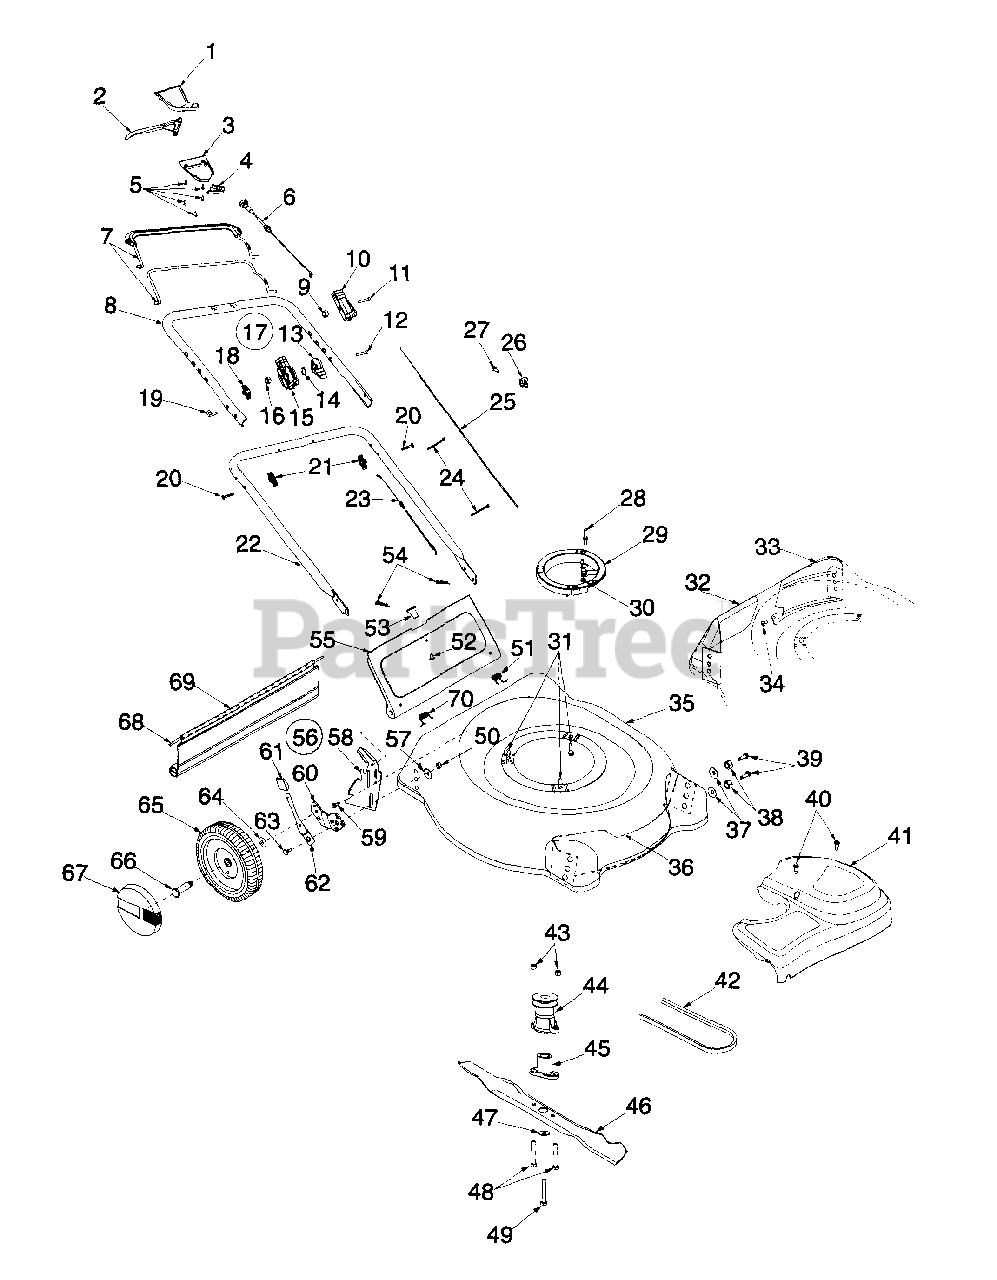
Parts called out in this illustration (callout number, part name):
1	Upper Drive Cover
2	Drive Lever
3	Lower Drive Cover
4	Mounting Cap
5	Screw #10-12:75
6	Drive Cable
9	Hex Lock Nut 1/4-20
10	Throttle Hsg. w/o Lever
11	Scr. Oval C-Sunk 1/4-20 x 1.31
12	Scr. Oval C-Sunk 1/4-20 x 1.81
13	Throttle Lever
14	Curved Washer .663 x .980 x .014
15	Throttle Housing
16	Hex Lock Nut 1/4-20 Thd.
17	Throttle Body Comp.
19	Eye Bolt 1/4-20
20	Carriage Bolt 5/16-18 x 2.0
21	Knob
23	Throttle Cable: 55"
24	Tie Cable
25	Control Cable 39"
26	Cable Clamp
27	Hex Screw: T: #10-32
28	Pin-Belt Keeper
29	Engine Spacer
30	Hex Nut 1/4-20 Thread
31	Tapp Screw w/Hex Lock Wash
34	Scr. AB: 1/4-14 .625 Trust
38	Bell Washer .39 x 1.13 x .062
39	Hex Screw 3/8-16 x .75
40	Screw #12 x .457
41	Trans Cover - Black
42	V-Belt
43	Hex Lock Nut 1/4-20
44	Drive Pulley
45	Blade Adapter
46	21" Mulching Blade w/star
47	Bell Washer .396 I.D. x 1.140 O.D. x
48	Hex Screw 1/4-20 x 1.50
49	Hex Screw 3/8-24 x 2.50
50	Hex Nut 3/8-16
51	Torsion Spring L.H.
52	Scr. Tr. Mach #10-24 x .380
54	Cotter Pin
58	Handle Brkt Ass'y - LH
59	Hex Screw w/wsh. 1/4-14 x .62
60	Pivot Bar - LH
61	Knob
62	Spring Lever
63	Shldr Screw .500 Dia x .434 Long
64	Bell Washer .380 x .880 x .062
65	Wheel 8 x 1.75 Disk Bar Grey
66	Shldr Screw .496 x 1.445
67	Hubcap: Euro Grey
68	Wire
69	Rear Flap
70	Torsion Spring R.H.
